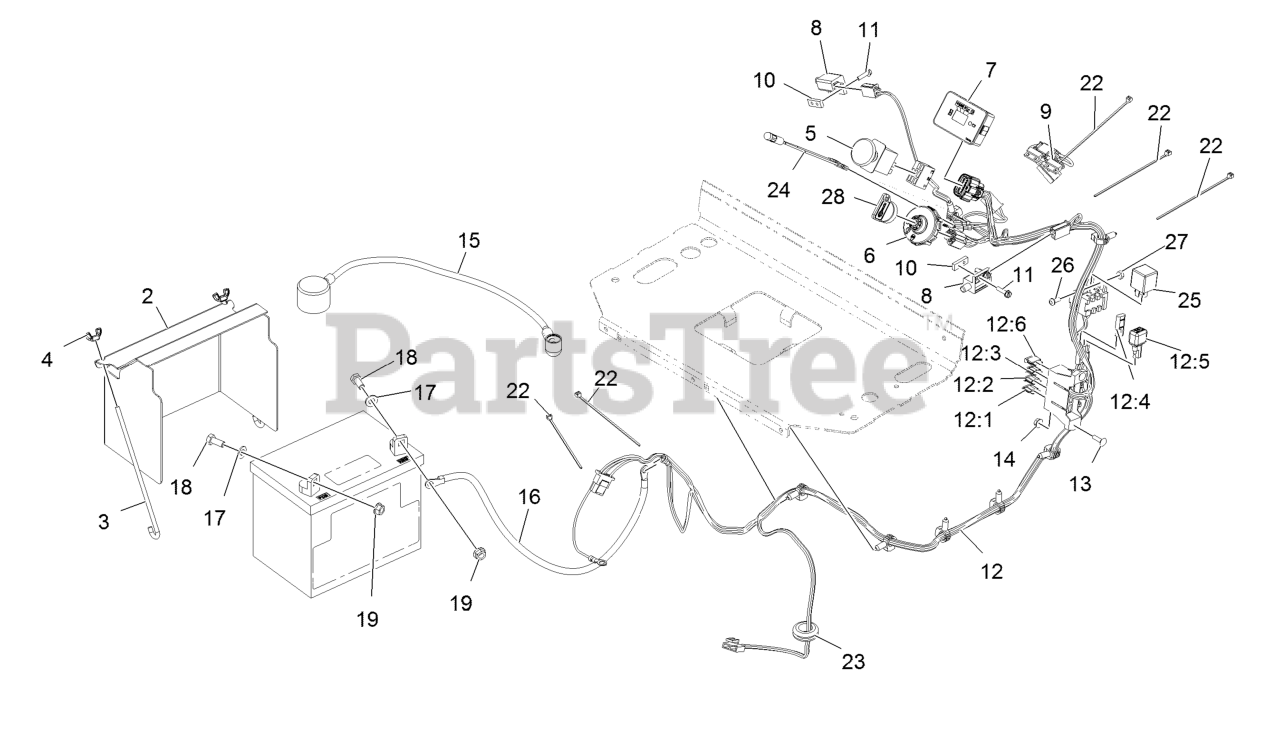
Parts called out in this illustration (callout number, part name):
2	COVER-BATTERY
3	BOLT-HOLDDOWN
4	WINGNUT
5	SWITCH-PTO, ON-ON
7	MODULE-HOUR METER
8	SWITCH-CLOSED, NORMALLY
9	HARNESS-SWITCH, REED
10	PLATE-TAPPED
11	SCREW-HWH
12	HARNESS-WIRE, EFI
12:1	FUSE-BLADE, 30 AMP
12:2	FUSE-BLADE, 25 AMP
12:3	FUSE-BLADE, 10 AMP
12:6	FUSE-BLADE, 15 AMP
13	SCREW-CARR
15	CABLE-BATTERY, POSITIVE
16	CABLE-BATTERY, BLACK
17	WASHER-PLAIN
18	SCREW-HH
19	NUT-HHF, SMOOTH
22	TIE-CABLE
23	GROMMET
24	INDICATOR-LED, RED
26	SCREW-PPH
27	NUT-LOCK, NI
28	KEY-IGNITION
